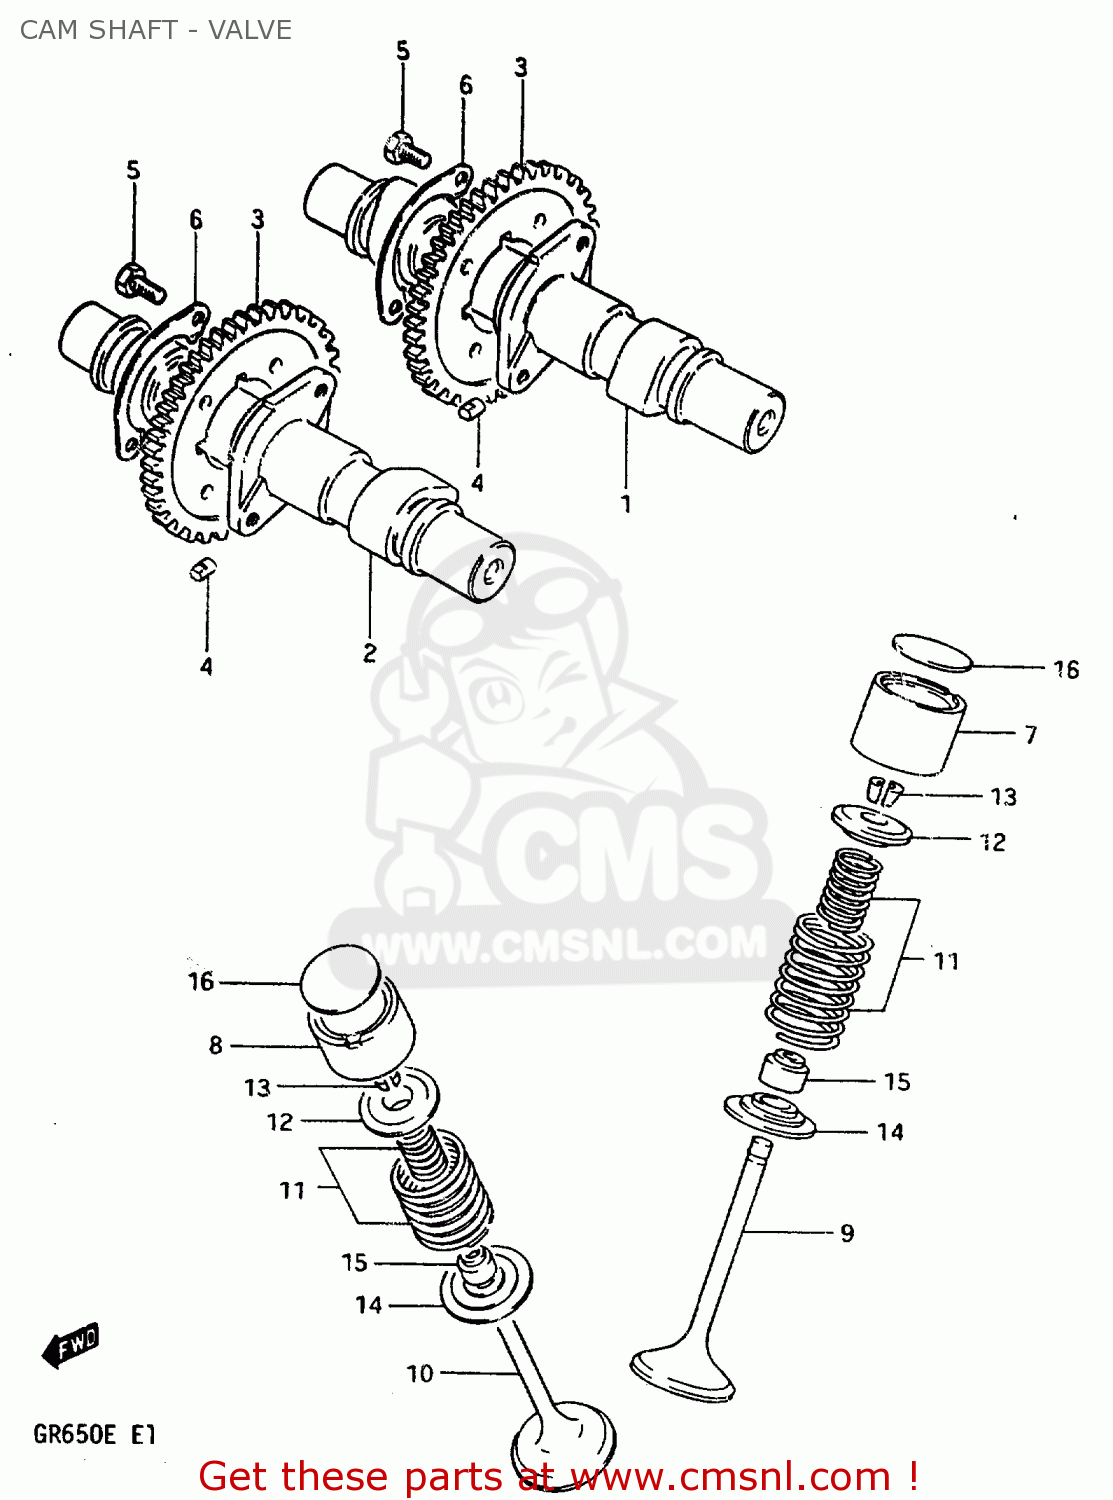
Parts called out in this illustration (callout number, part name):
1	CAMSHAFT,INTAKE
2	CAMSHAFT,EXHAUST
3	SPROCKET,INTAKE CAMSHAFT
4	PIN,SPROCKET
5	BOLT(6X12.5)
6	WASHER,CAM CHAIN SPROCKET
7	TAPPET,INTAKE
8	TAPPET
9	VALVE,INTAKE
10	VALVE,EXHAUST
11	SPRING SET,VALVE
12	RETAINER,VALVE SPRING
13	COTTER VALVE
14	SEAT,VALVE SPRING
15	SEAL,OIL(7X14.4X9)
16	SHIM,TAPPET
